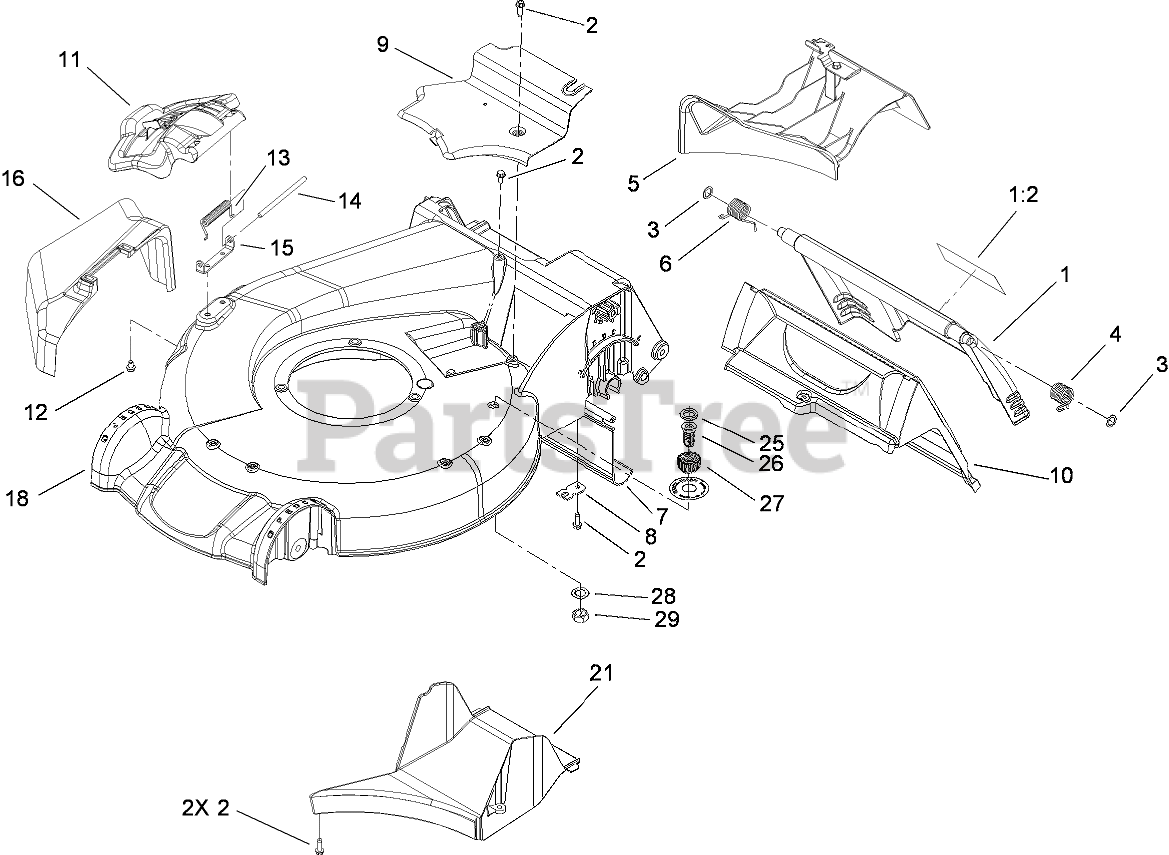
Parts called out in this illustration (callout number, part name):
1	REAR DOOR ASM
1:2	DECAL-WARNING
2	SCREW-HWHTF
3	WASHER-NYLON
4	SPRING-TORSION
5	MULCH PLUG ASM
6	SPRING-TORSION
7	SHIELD-TRAILING
8	BRACKET-CABLE, TRACTION
9	COVER-BELT
11	DISCHARGE DOOR ASM
12	SCREW-HWH
13	SPRING-TORSION
14	ROD-COVER
15	BRACKET-COVER
16	CHUTE-DISCHARGE, SIDE
18	HOUSING ASM
21	TUNNEL-DISCHARGE
25	WASHER-SEAL, WASHOUT PORT
26	PORT-WASHOUT
27	COUPLING-HOSE, WASHOUT PORT
28	WASHER-TOOTH, INTERNAL
29	NUT-JAM
